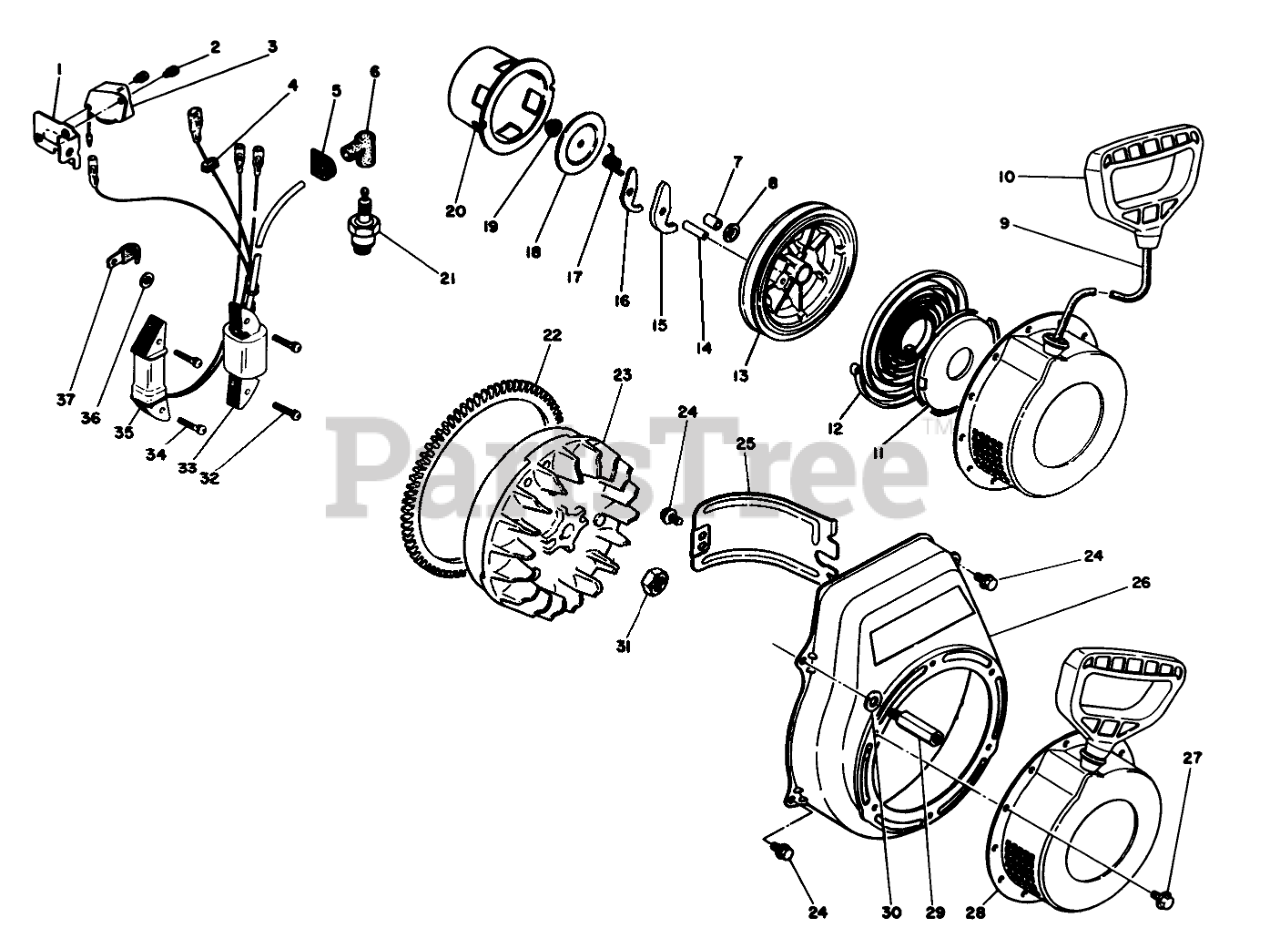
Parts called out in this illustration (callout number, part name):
1	Bracket-Unit
2	Screw & Washer
3	BRACKET
4	Grommet
5	GROMMET
7	SHAFT
8	WASHER
12	SPRING
15	RATCHET
16	RATCHET
17	SPRING
18	FRICTION PLATE
20	STARTER PULLEY
21	SPARK PLUG
22	RING GEAR
23	Flywheel
25	CYLINDER BAFFLE
26	COVER
28	Recoil Starter Assembly (Incl. Ref. #7-20)
30	Washer
32	SCREW & WASHER
33	Coil-Ignition (Incl. Ref. #4)
34	SCREW & WASHER
35	LIGHTING COIL
37	CLAMP
